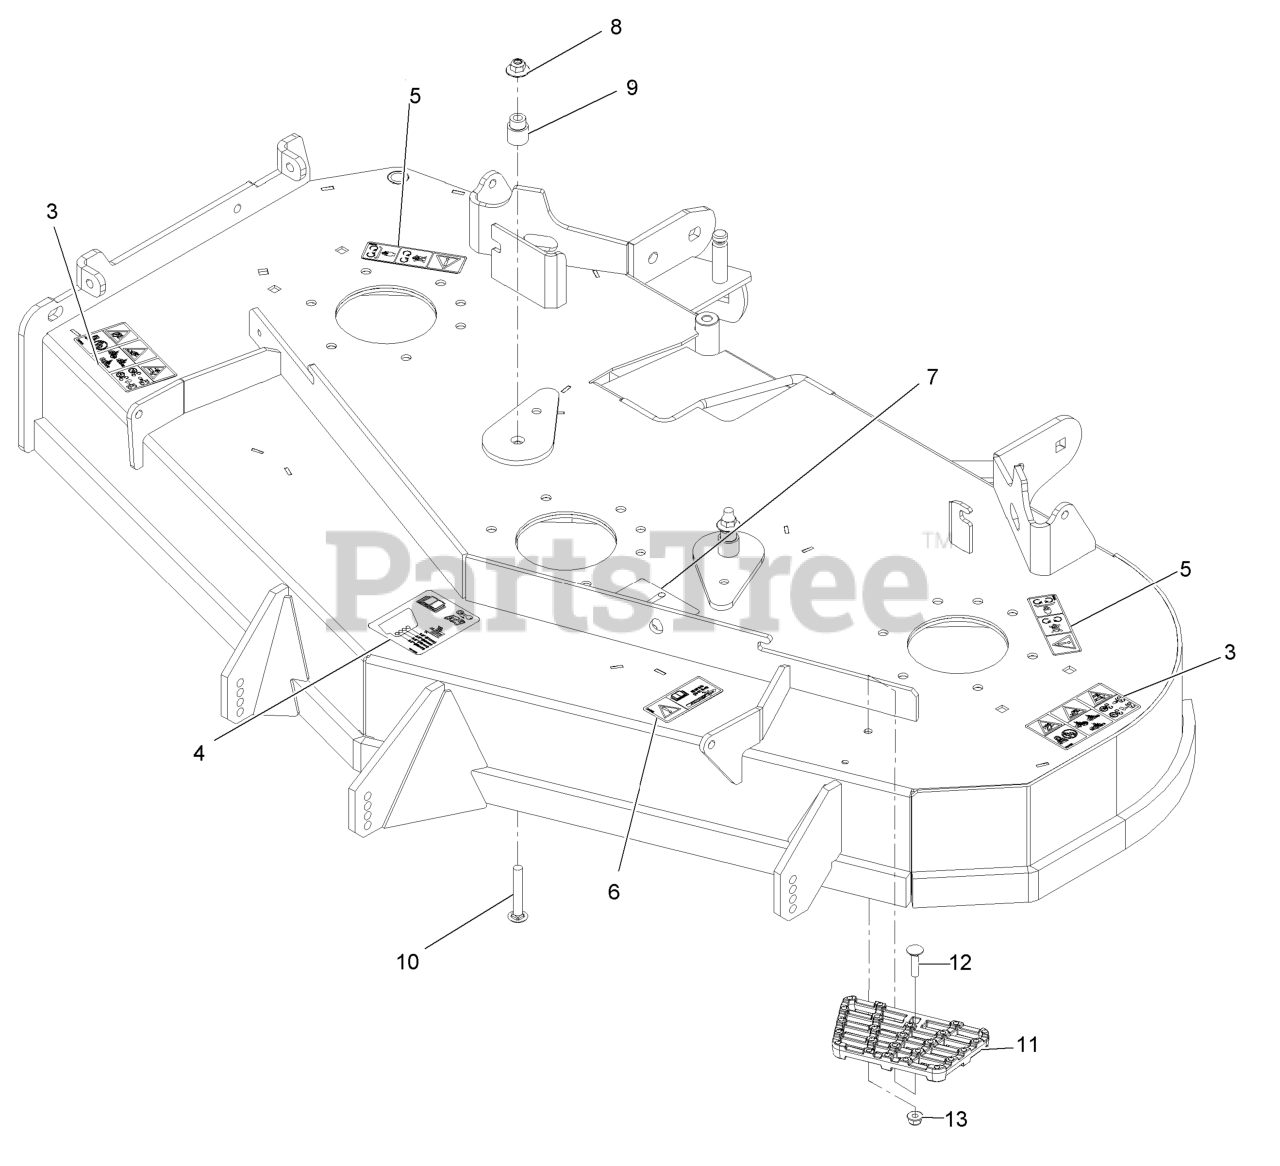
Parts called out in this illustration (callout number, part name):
3	Decal-Danger Thrown Objects
4	Decal-Roller, Anti-Scalp
5	Decal-Missing, Cover
6	Decal-Bolt Torque
7	Decal-Belt Routing
8	Nut-Nyloc 3/8-16 Flg
9	Bushing, Idler
10	Bolt-Carriage 3/8-16 X 2 1/2
11	Step-Deck
12	Bolt-Carriage 5/16-18 X 1 1/4
13	Nut-Nyloc 5/16-18 Flg
